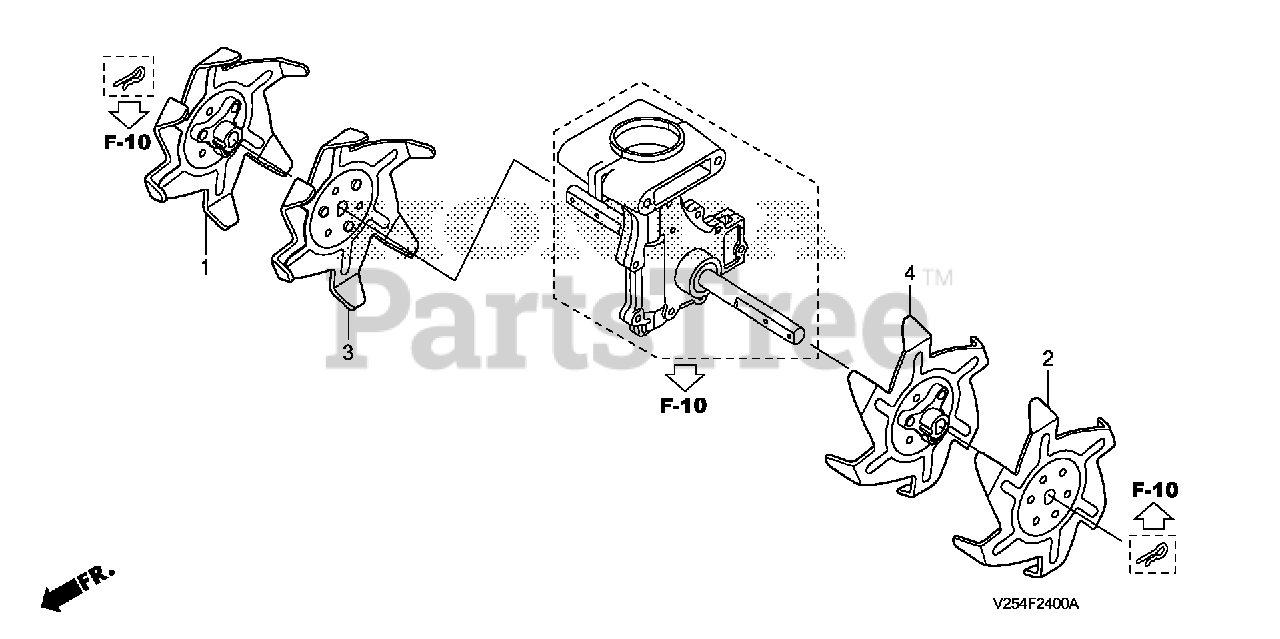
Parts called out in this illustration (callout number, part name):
1	TINE, R. (OUTER)
2	TINE, L. (OUTER)
3	TINE, R. (INNER)
4	TINE, L. (INNER)
